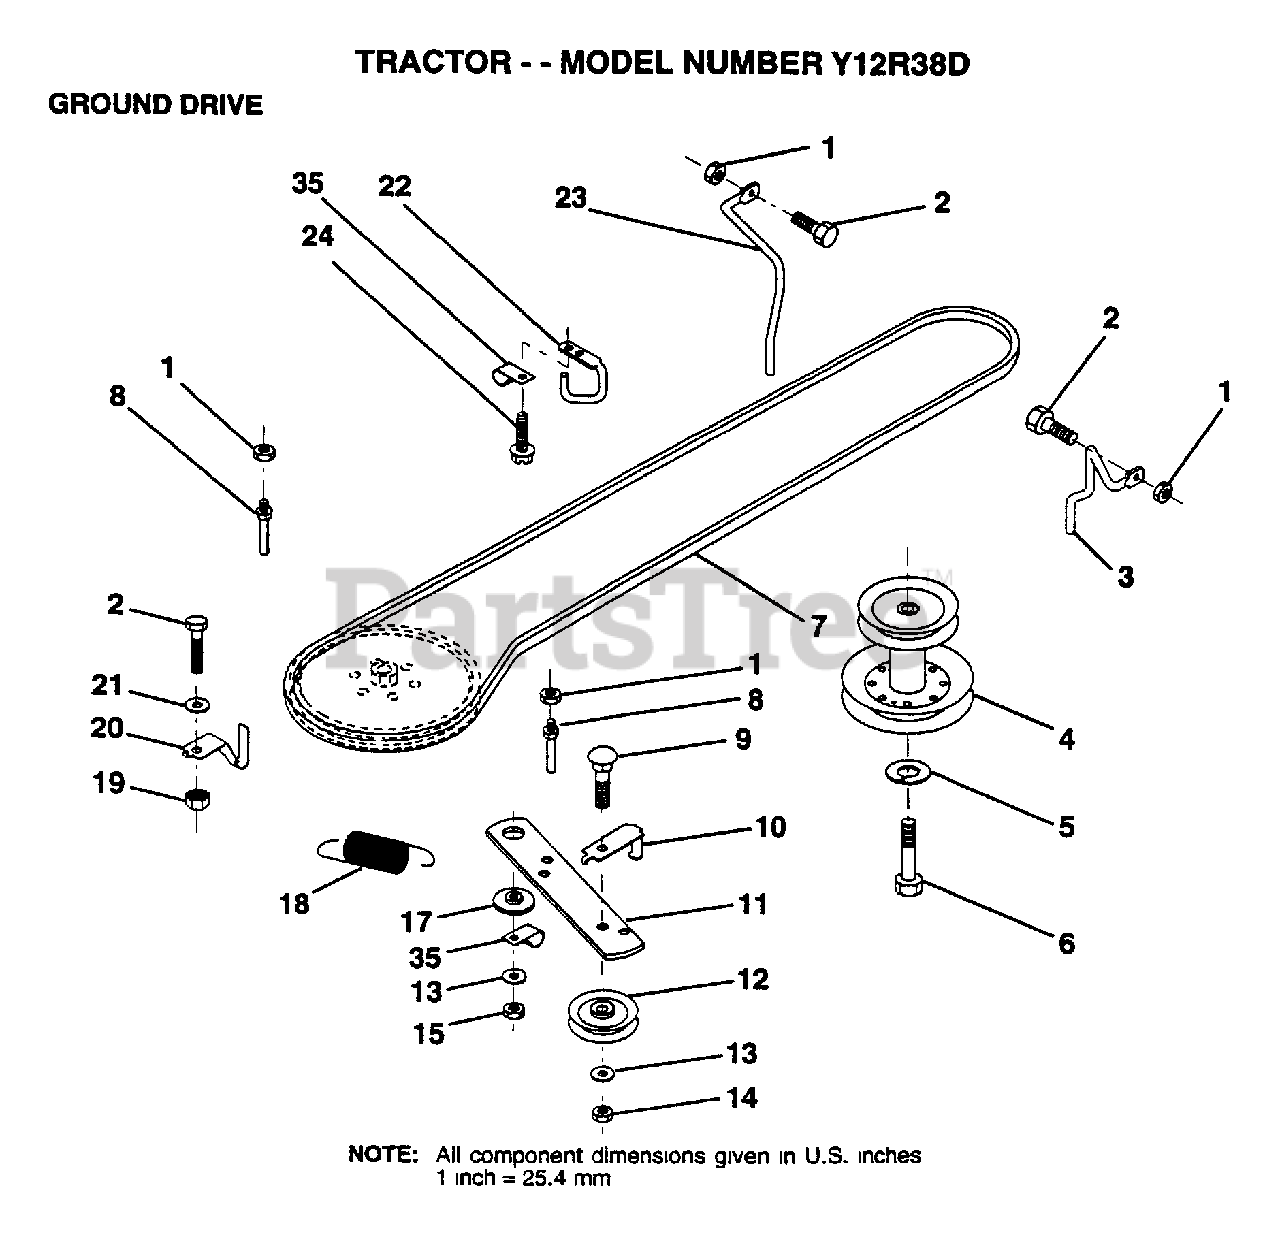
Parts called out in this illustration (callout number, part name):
2	BOLT
3	KEEPER.BELT.FRT.
4	PULLEY.ENGINE.LR
5	LOCKWASHER
6	HEX BOLT
7	BELT
8	"KEEPER,DRIVE BELT"
9	BOLT
10	"KEEP,IDLER DR BEL"
11	ARM IDLER CLUT GD
12	PULLEY.IDLER.FLAT
13	WASHER
14	LOCKNUT
17	SPACER RETAINER
20	KEEPER.BELT.T/A
21	WASHER
22	"KEEPER,FRA DR BEL"
23	KEEPER.BELT.FRT.L
24	SCREW
35	CLIP INSULATOR
